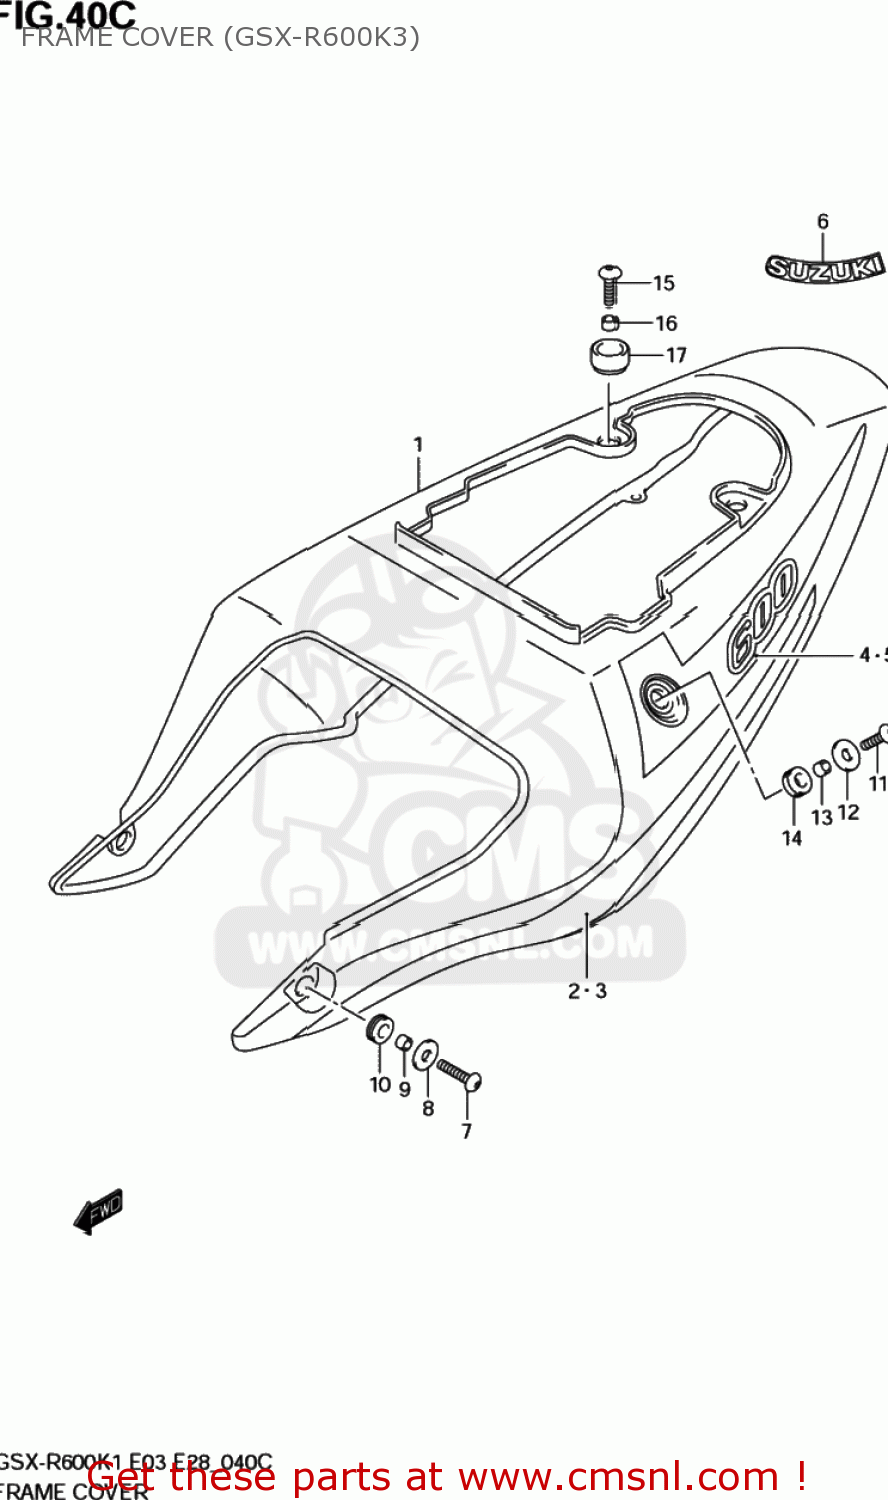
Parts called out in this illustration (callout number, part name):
1	COVER ASSY,FRAME(WHITE)
2	TAPE,FRAME COVER STRIPE,R
3	TAPE,FRAME COVER STRIPE,L
4	TAPE,FRAME COVER,R
5	TAPE,FRAME COVER,L
6	EMBLEM,SUZUKI
7	SCREW(6X30)
8	WASHER(6.5X20X2)
9	SPACER(6.5X10X7)
10	CUSHION,FRAME COVER FR
11	SCREW(6X25)
12	WASHER(6.5X20X2)
13	SPACER(6.5X10X7)
14	CUSHION,FRAME COVER SIDE
15	SCREW(6X25)
16	SPACER(6.5X10X9.4)
17	CUSHION
